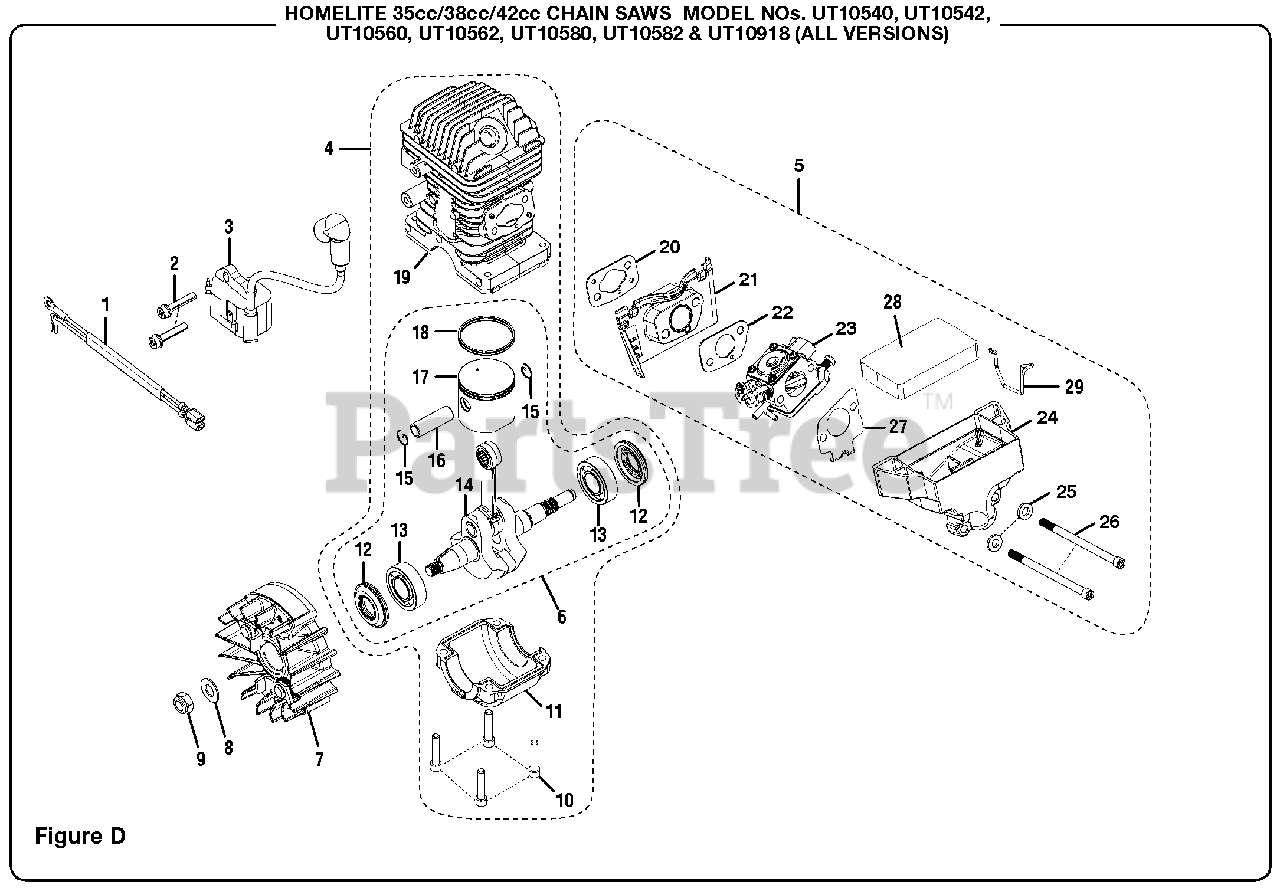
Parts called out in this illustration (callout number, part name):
1	Ignition Switch Harness
2	Bolt (M5 x 25.4 mm)
3	Ignition Module
4	Short Block Assembly
5	Intake Assembly
6	Crankshaft & Piston Assembly
7	Flywheel Assembly
8	Washer
9	Flywheel Nut
10	Screw (M5 x 24 mm)
11	Crankshaft Case
12	Crankshaft Seal
13	Ball Bearing
14	Crankshaft & Rod Assembly
15	Spring Retainer
16	Piston Pin
18	Piston Ring
20	Intake Gasket
22	Carburetor Gasket
23	Carburetor
24	Air Filter Box
26	Bolt (M5 x 76 mm)
27	Carb Bracket
28	Air Filter
29	Throttle Rod
